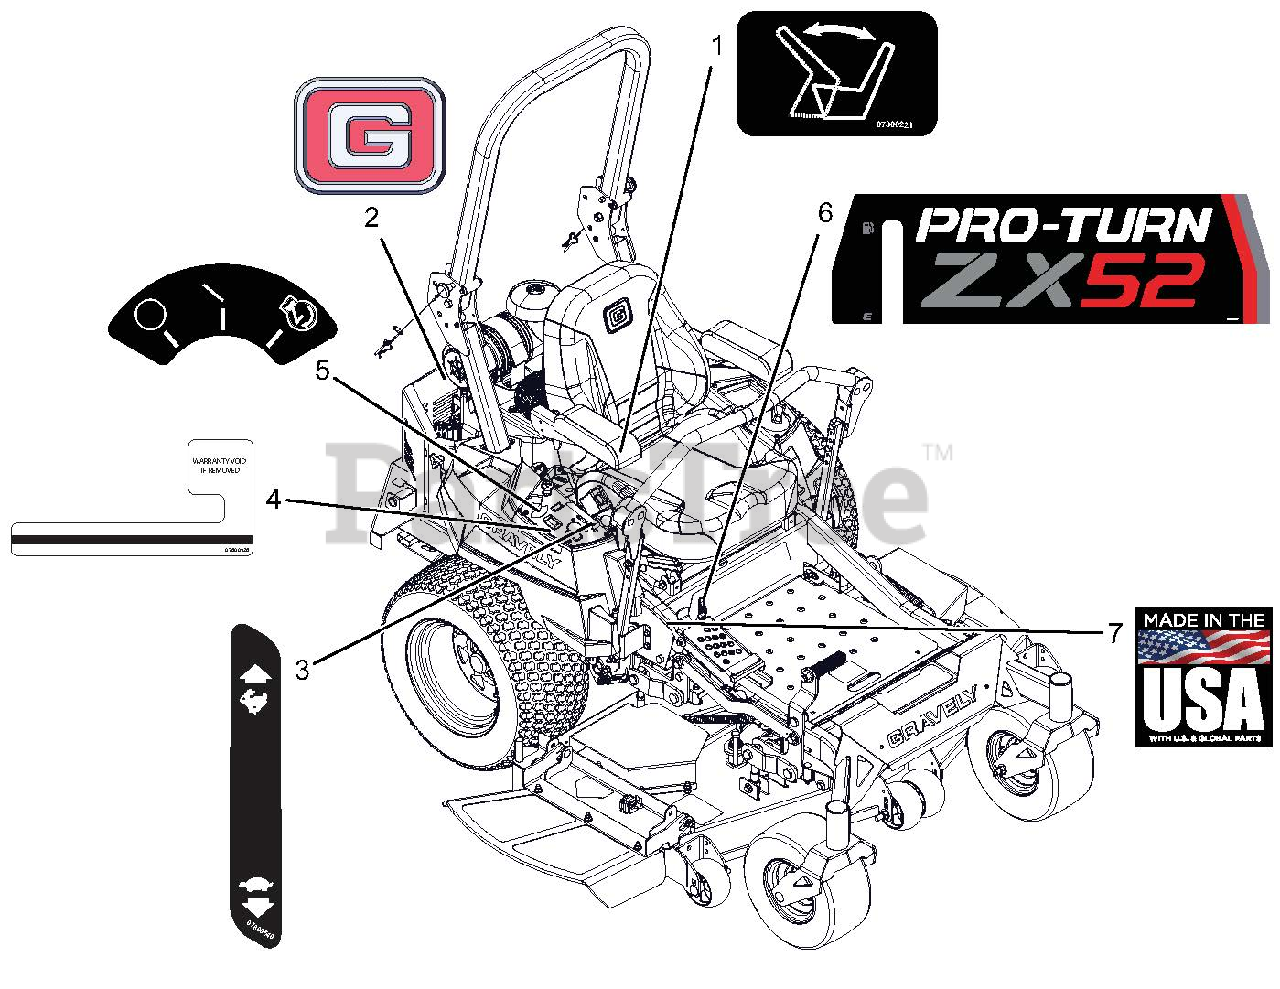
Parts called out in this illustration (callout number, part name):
1	DECAL - SEAT RELEASE
2	DECAL, GRAVELY BRAND
3	DECAL, DASH DECAL
4	DECAL,HOURMETER - SECURITY
5	DECAL, KEYSWITCH
6	DECAL, PROTURN ZX 52
7	DECAL, MADE IN USA
